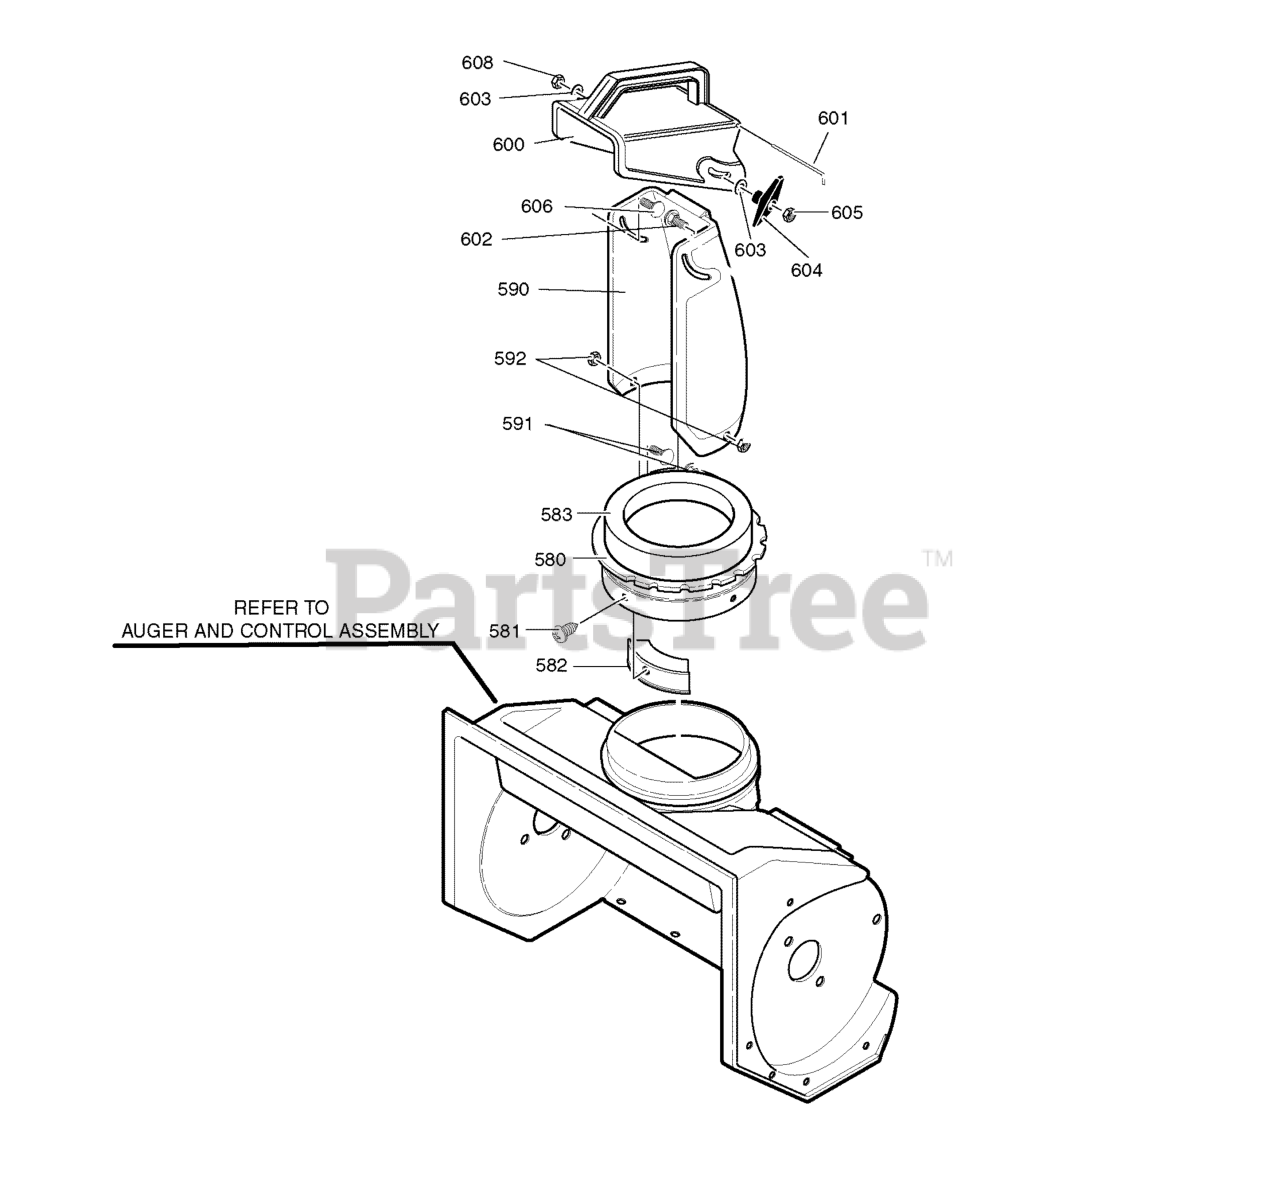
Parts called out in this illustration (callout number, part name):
580	CHUTE RING
581	SCREW, #10 X .50
582	GUIDE, CHUTE
583	DONUT, FOAM 21 PLAST A
590	CHUTE, DEFLECTOR LOWER
591	SCREW 1/4-20 X .75
592	NUT, 1/4-20, HEX CONTROL LOCK
600	CHUTE DELFECTOR, UPPER
601	WIRE FORM, HINGE 5.75
602	BOLT, 5/16-18 X 1.25 CARRIAGE
603	WASHER, FLAT .349 X .69 X .066
604	KNOB, WING
605	NUT, 5/16-18
606	SCREW, 5/16-18 x 0.75
608	NUT, 5/16-18, HEX CONTROL LOCK
